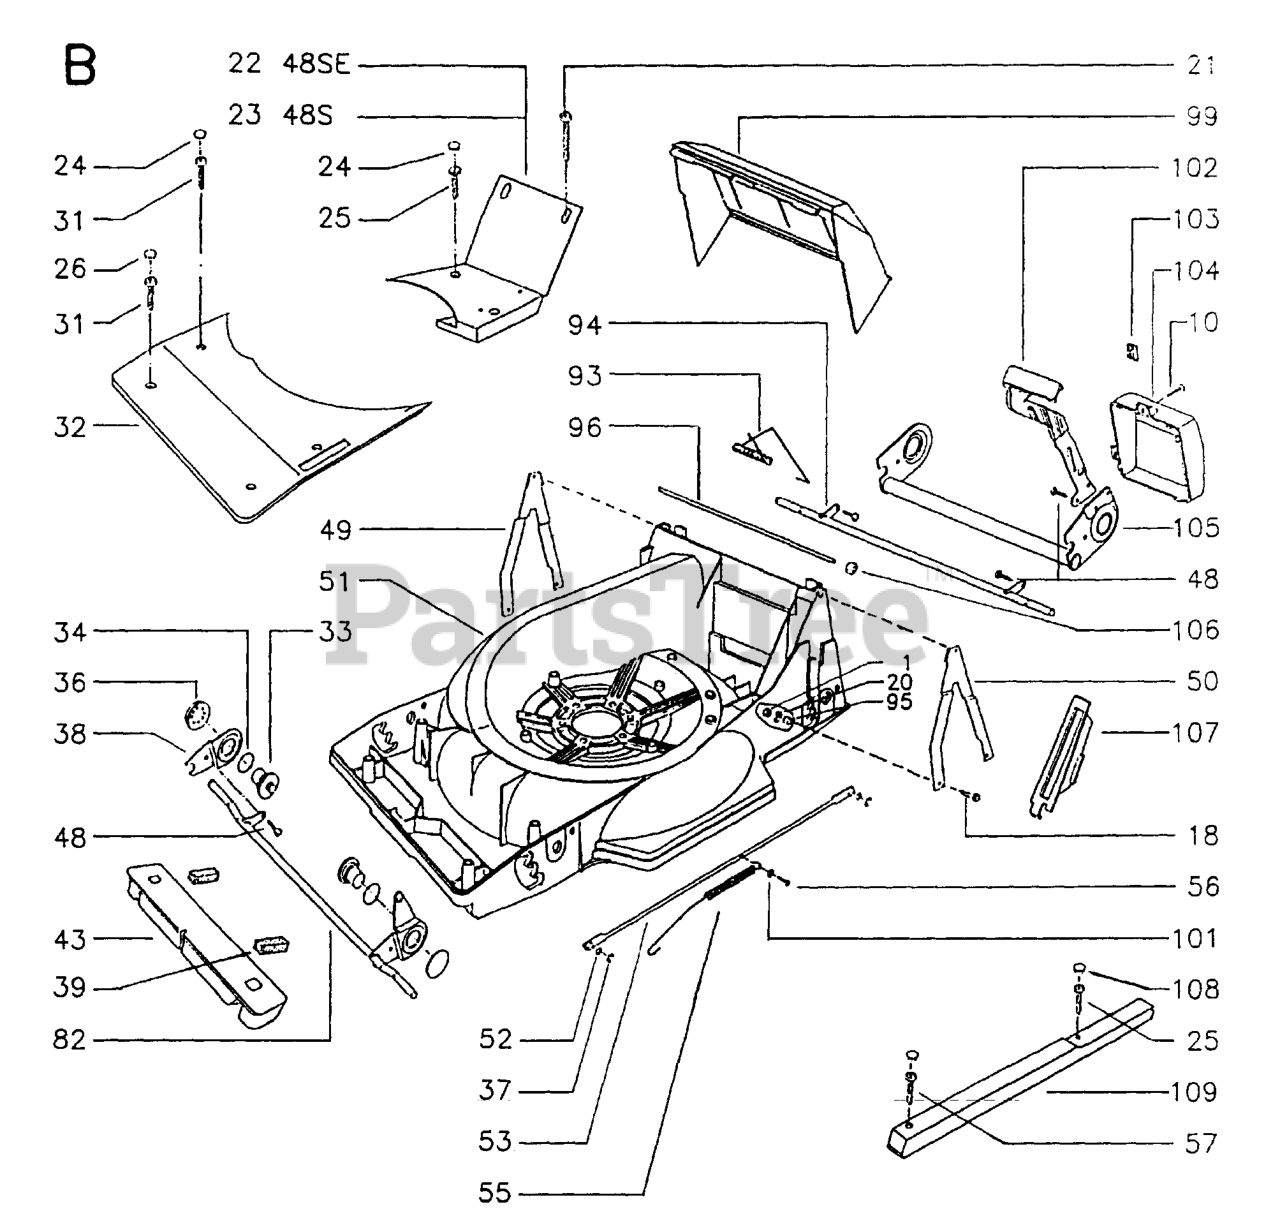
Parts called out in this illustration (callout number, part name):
1	LOCKNUT M8
22	BRACKET 48SE
23	BRACKET 48S
56	SCREW TAPTITE
103	LOCK PLATE
104	REAR COVER R48
107	HEIGHT ADJ. COVER
